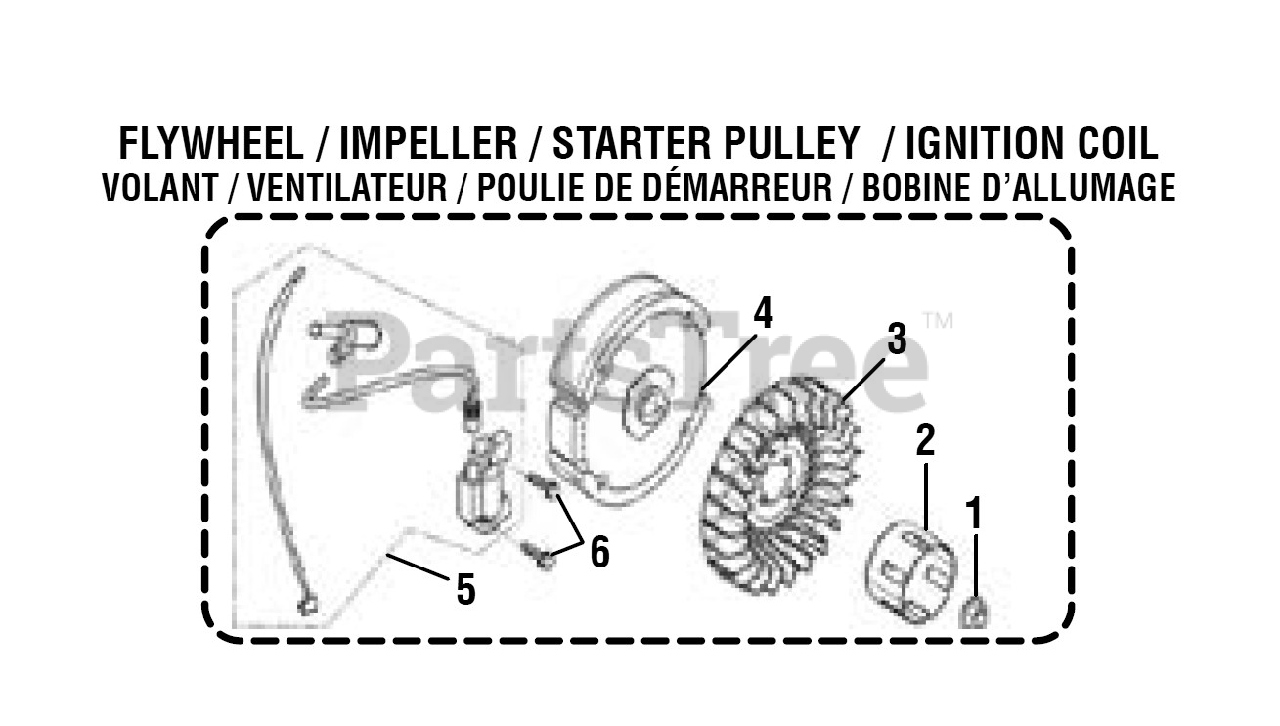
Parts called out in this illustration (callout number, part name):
1	Flywheel Nut
2	Starter Pulley
3	Impeller
4	Flywheel Assembly
5	Ignition Coil
